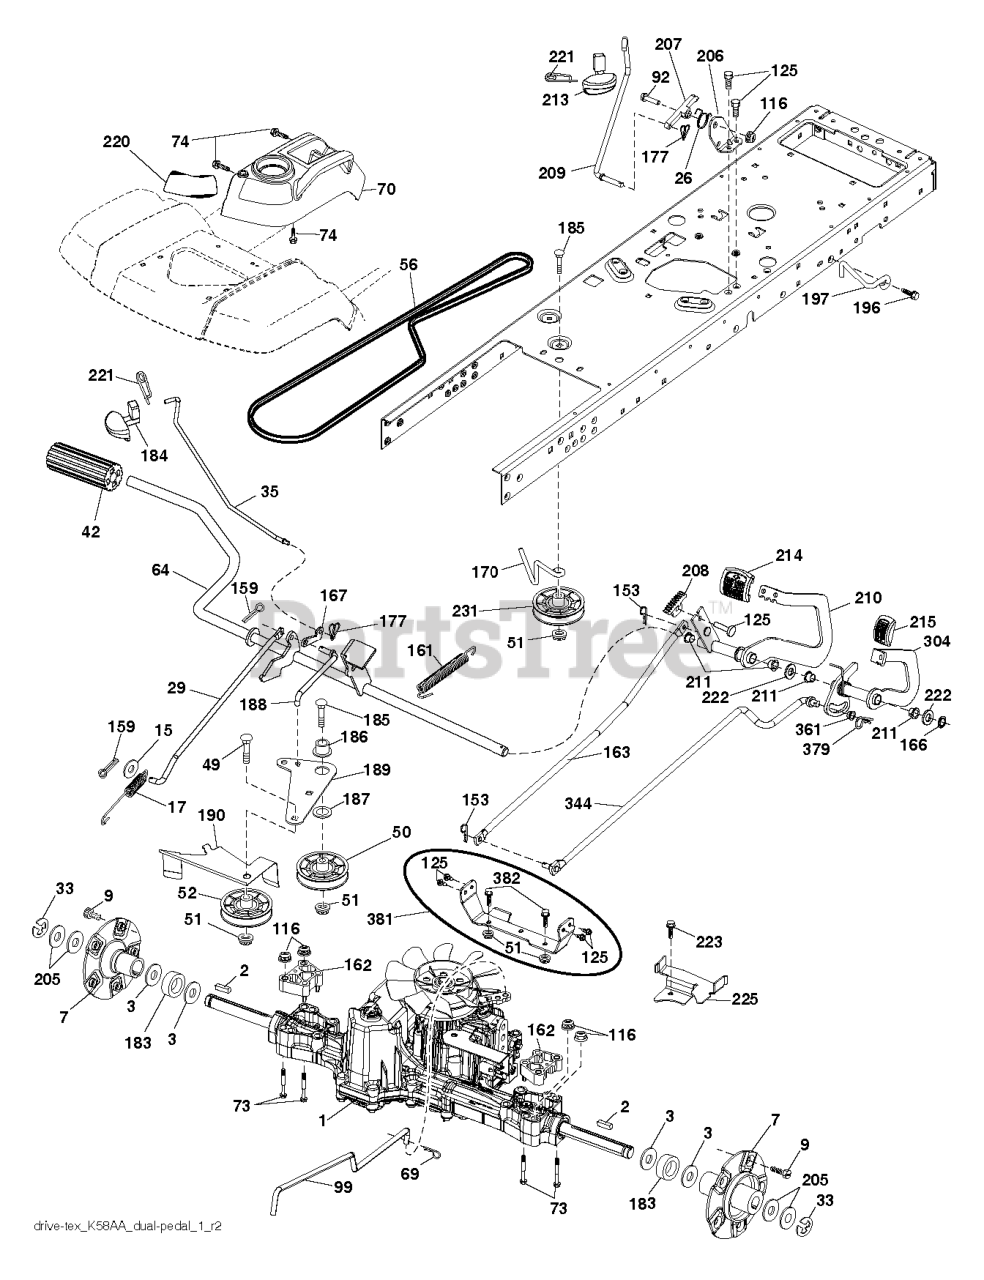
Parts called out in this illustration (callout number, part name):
2	KEY, 1/4 SQ X 1 1/4
7	HUB.PNT.GT.PM.1IN.AXLE.E-DIP
15	WASHER PLAIN WASHER 3/8 X 0.08
17	SPRING.BRAKE.K46.GREEN
26	SPRING.RETURN.CRUISE
29	ROD.BRAKE.K46
33	E RING HYT
42	PEDAL COVER
50	IDLER.FLAT.910.OFFSET
51	NUT LOCK FLG 3/8-16 UNC
52	IDLER.V-GROOVE.910.OFFSET
64	SHAFT.ASM.PEDAL.BRK.CNTR
69	HAIRPIN.SOFT.ZINC.059X1.125
70	CONSOLE.ASM.RH.GT.FC.HUSQ
73	BOLT.HEX.FLNG.5/16-18X3.75
125	SCREW
153	RETAINER M
161	SPRING, RETURN LT
166	NUT.PUSH.625
167	LATCH.BRAKE.SPRING
170	KEEPER.CENTER SPAN.1.688
177	PIN COTTER;LOCKING;BOWTIE;1IN
183	SPACER.SPLIT;1.00.ID 1.75"
184	HANDLE.PARKING.BRAKE.H (BLK)
186	SPACER.RETAINER
188	LINK.CLUTCH.GROUND DRIVE.LONG
189	BELLCRANK.GROUND.DRIVE.TEX.
190	KEEPER.BELLCRANK.DRIVE
196	SCREW 3/8-16X1
206	BRACKET.MOUNT.CRUISE.LATCH
211	BEARING.NYLON
213	KNOB.CONTROL.CRUSIE.HU
214	PEDAL.FORWARD.PAD.TEX
220	REFLECTOR.RH.TEX GT
221	RETAINER.SPRING.CLIP.H
222	WASHER 21/32 X 1-1/4 X 10 GA.
225	KEEPER.BELT.TRANSAXLE.K46
231	IDLER.V-GROOVE.1.688.OFFSET
381	Service Kit
